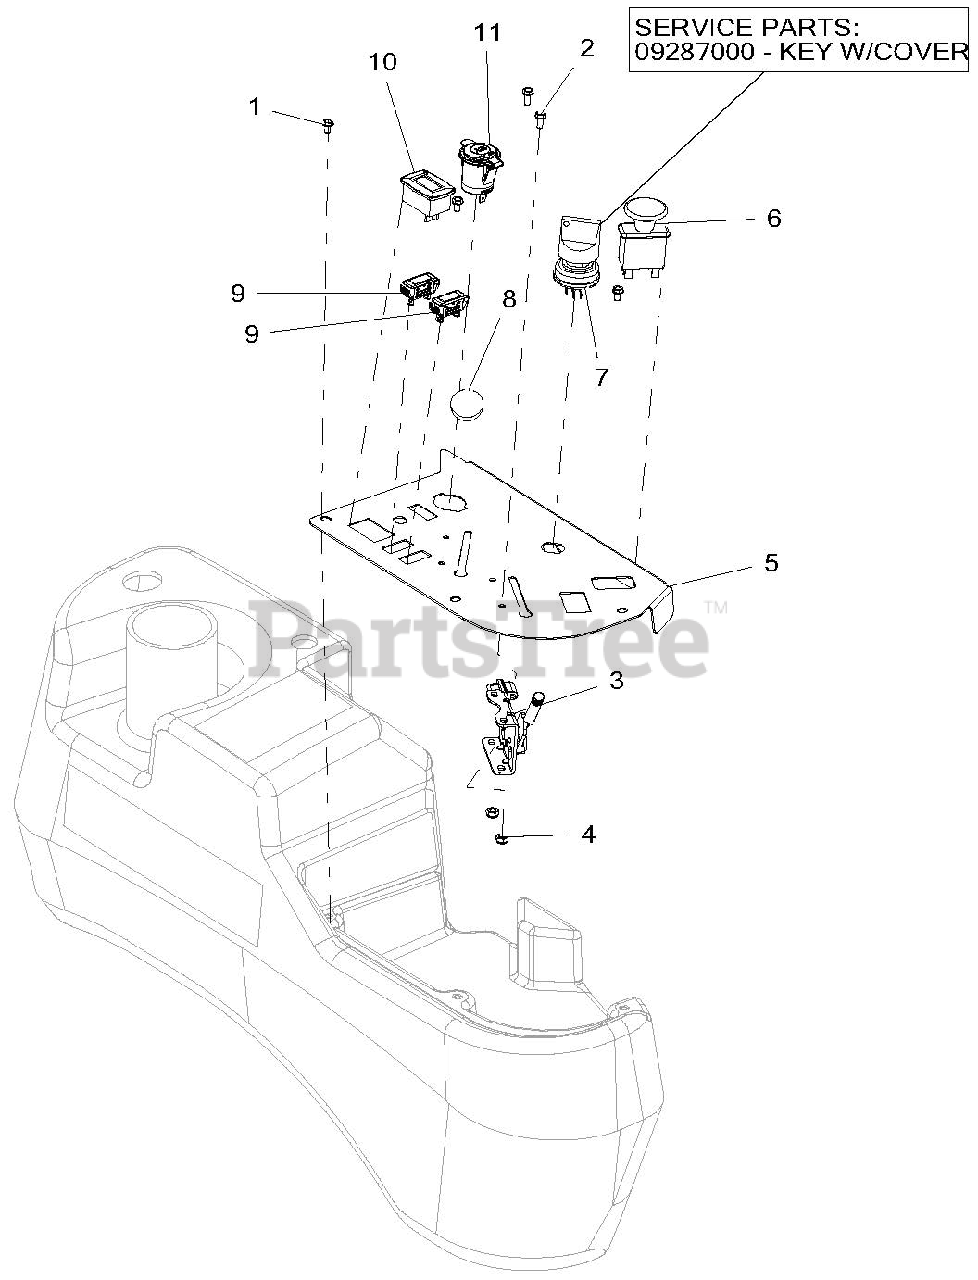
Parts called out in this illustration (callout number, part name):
1	SCR-MCH 10-24X.38 HWHSTAINLESS
2	@SCR-MCH 10-24X.50 HWH YWZC
3	CABLE, PRO-CONTROL THROTTLE
4	NUT-LK-NYL #10-24 YWZC
5	PANEL, CONTROL
6	SWITCH, CLUTCH
7	SWITCH, IGNITION
7	KEY W/COVER
8	KNOB, CONTROL BLACK .38-16X.50
9	LIGHT, INDICATOR
10	METER, HOUR W/MAINTENANCE
11	PORT, 12 VOLT POWER
